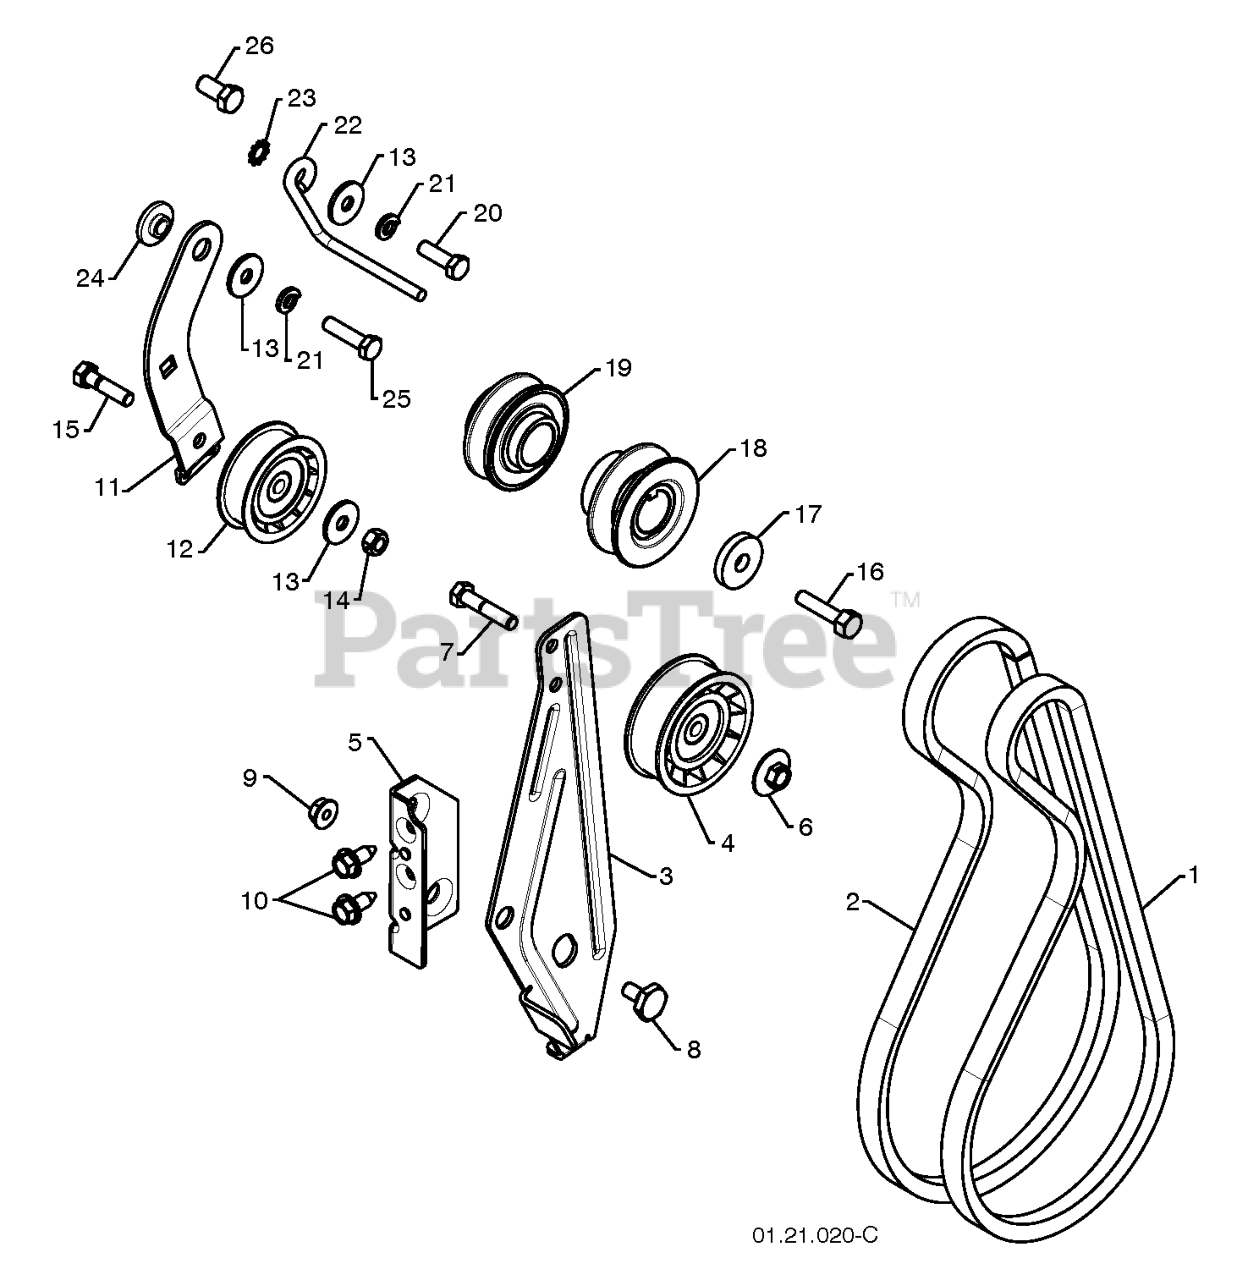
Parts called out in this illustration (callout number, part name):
1	HANDLE.ASM.UP.CREASED.GRE.W/GR
2	CABLE.MZR.W/KEY.START SW.51.62
3	BRACKET UPSTOP
4	PLUG.MULCH.22RD
5	TIE GUIDE
6	KNOB, DEFLECTOR
8	CONTROL BAR
9	REAR DOOR ASSY
10	RIVET BLIND
11	SCREW.HXTAP.10-24
12	SCREW 14-20 X 5/8
14	PLATE.BACK
15	SIDE BAFFLE
16	DISCHARGE BAFFLE
17	REAR BAFFLE
18	NUT
19	RB GUIDE.ROPE.STD.BLK.ZIN WSL
20	SKIRT.REAR.22RD/SD.FO/VE
21	SPRING.LH.22.REAR.DOOR.EZ.EMPT
24	SPRING.RH.22.REAR.DOOR.EZ.
25	NUT.HEX.FLANGE.3/8-16.LO(3 2)
27	WHEEL & TIRES ASSY, FRONT
28	BOLT SHOULDER 3/8 -16X1
29	WASHER.CURVED.CYLINDRICAL
30	AXLE ARM ASSY.
31	SELECTOR KNOB
32	SELECTOR SPRING, FRONT
33	DOOR.MULCH.22.REAR.FWGD.GREY
34	SPACER.HEIGHT.ADJUSTER
35	WHEEL ADJUSTING BRACKET
36	BRACKET.ASM.HINGE.21.FWGD.
37	SCREW
38	DEFLECTOR.CLIPPING.22.GREY
39	BRACKET.ASM.HDL.LT.EZEM.22.ORA
40	BRACKET.ASM.HDL.RT.EZEM.22.ORN
41	BOLT 3/8-16X1-1/8
42	SPRING.TORSION
43	LOCKNUT.NYLOC.1/4-20
44	HOUSING.22.TORUS.FWD.ORANGE.WA
45	ROD.HINGE.21
46	BLADE ADAPTOR / PULLEY
47	BLADE.22.MULCH.STANDARD
48	WASHER,HARDEN
49	LOCKWASHER
50	SCREW, HEX HD 3/8-24 X 1-3/8
51	FRONT BAFFLE KIT
52	DANGER DECAL
53	SCREW 1/4X20
54	WASHER.FLAT.1/2
55	LOCKNUT
56	HINGE SCREW
57	HAIRPIN COTTER
58	HANDLE.LOWER.PNT
59	BOLT, HANDLE 5/16-18X1.75
61	BRACKET
62	DEBRIS SHIELD
63	SCREW.HEX.WSH
65	O-RING..070X.487.NEOPRENE
67	CLIP.WIREFORM.PACK.TOR
68	WHEEL ADJUSTING BRACKET LH
69	CLIP.CABLE.BLK
70	GRIP, FOAM
75	SCREW.(COMBINATION CONTROL)
76	KEY.MOLDED
77	NUT.CAP.SNAP-ON.KEY START
78	KIT.CONTROL.COMBI.KEYW/HARNESS
79	HARNESS.WIRING.CONTROL
